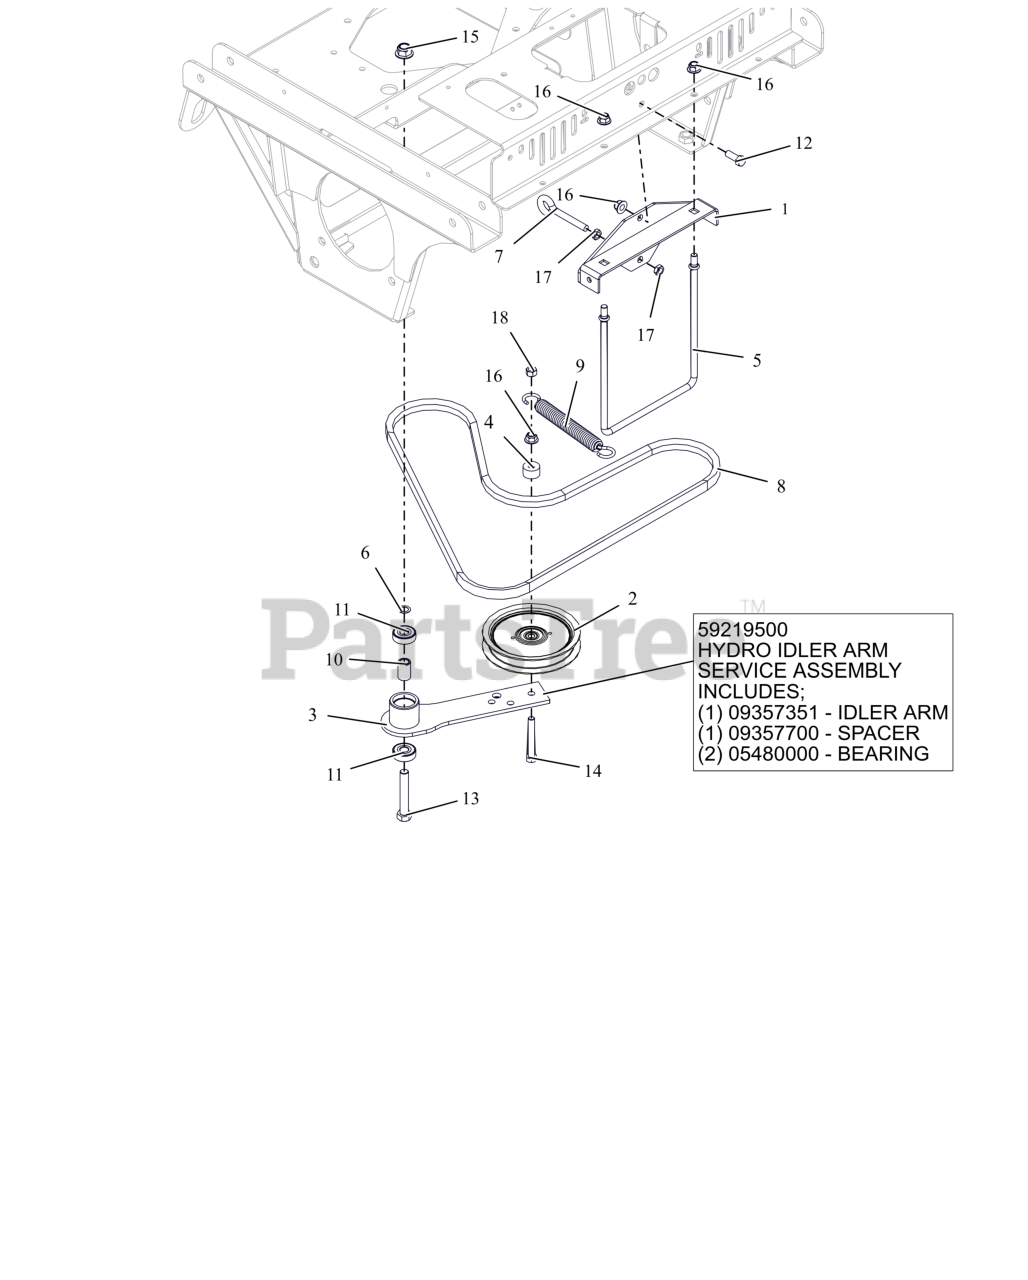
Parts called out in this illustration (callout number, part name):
1	SPRING ANCHOR BRKT WMT - BLACK
2	IDLER, FLAT-5.00X.75
3	HYDRO DRIVE IDLER ARM WMT- BLK
3	KIT, HYDRO IDLER ARM PT200/400
4	SPACER .390X1.000X.562
5	ROD, BRAKE MTG
6	WASHER, .500X.750X.020 THRUST
7	BLT-EYE .375-16X2.50 YWZC
8	V-BELT, COGGED B-RAW EDGE
9	SPRING, EXTENSION
10	SPACER .510 X .75 X 1.1485
11	BRG-BALL .500X1.38X.437
12	BLT,HEX .38-16X1.00 G5 ZCC
13	BLT, HEX .50-13X3.00 G5 ZCC
14	BLT, HEX .38-16X2.75 G5 ZCC
15	NUT,NYL-FLG .50-13 GF ZCC
16	NUT,NYL-FLG .38-16 GF ZCC
17	NUT-JAM .375-16 G2 ZCC
18	NUT-LK-CTR .38-16 ZC120
